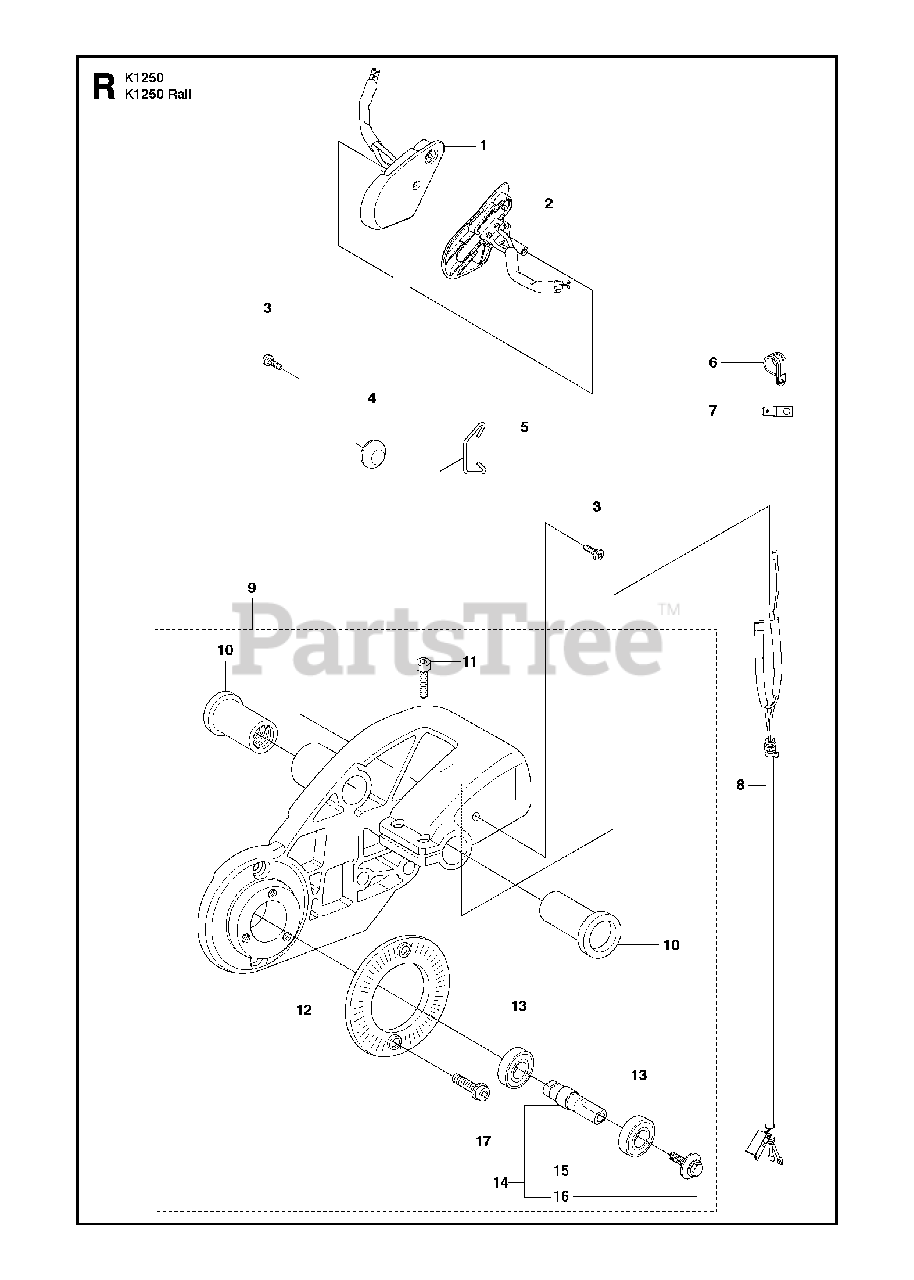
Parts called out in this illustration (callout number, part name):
1	STOP SWITCHRH
2	STOP SWITCHLH
3	SCREW CRPANT
4	SPACING BLOCK
9	BEARING HOUSING"14"" Rail"
9	BEARING HOUSING"14"" Rail Stop Switch, Incl. 10 - 14"
9	BEARING HOUSING"16"" Rail"
9	BEARING HOUSING"16"" Rail Stop Switch, Incl. 10 - 14"
9	BEARING HOUSING"16"" Rail, USA only"
11	SCREW IHSCFM
13	BALL BEARING
14	SHAFTIncl. 15 - 16
17	SCREW IHSCFM
